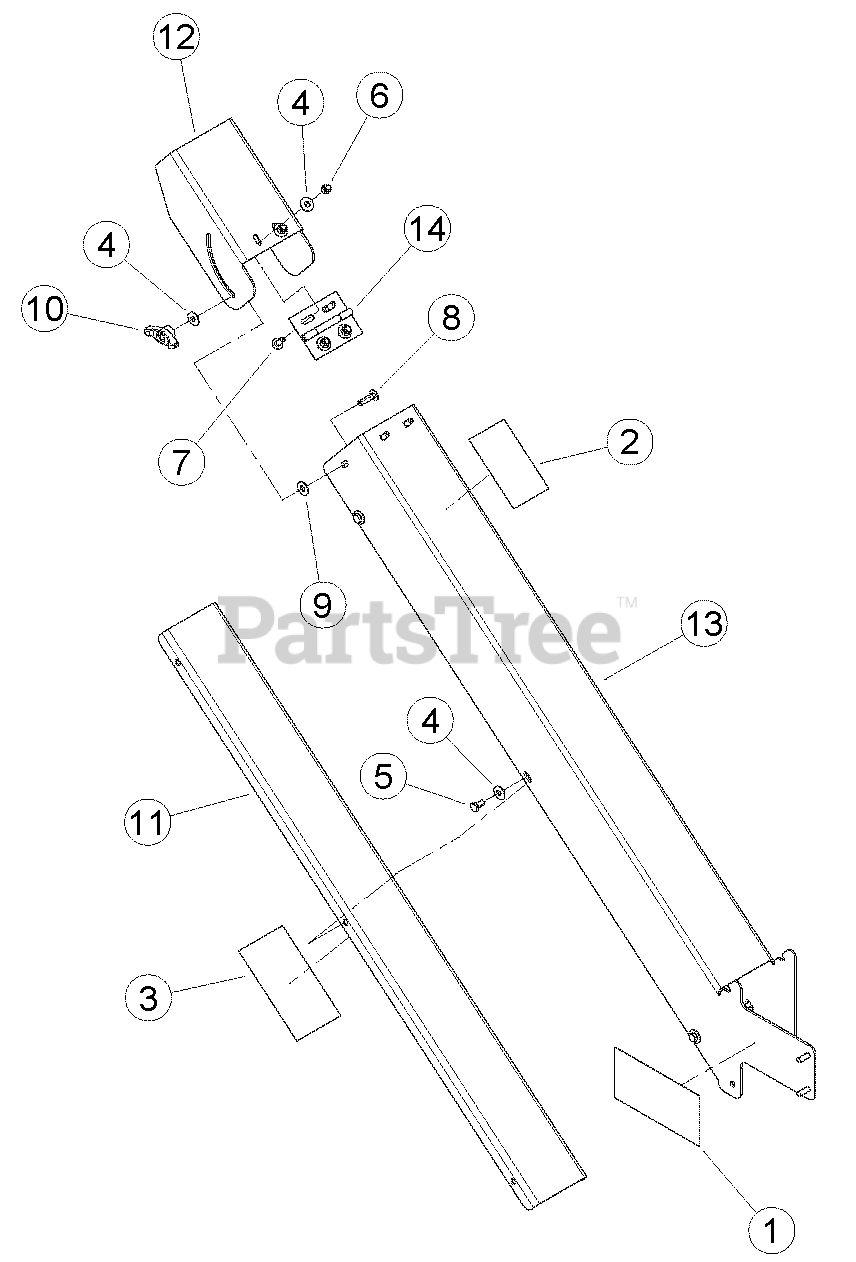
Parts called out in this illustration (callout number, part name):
1	DECAL, KNIFE ACCESS ISO
2	DECAL, DISCHARGE ISO
3	DECAL, BLADE DANGER ISO
4	WASHER, 5/16" FLAT ZP
5	BOLT,5/16 X 5/8 GR5 HEX CPS ZP
6	KNOB, SPOUT 5/16-18
7	NUT, 5/16" NE NYLOCK ZP
8	BOLT, 5/16X3/4 GR5 NC ZP CRG
9	BOLT, 5/16 X 1-1/4" GR5 ZP CRG
10	WASHER, 5/16"ID 7/8"OD NYLON FLAT
11	WELDMENT, TOP DISCHARGE CHUTE
12	CAP, DISCHARGE
13	WELDMENT, CHIPPER DISCHARGE
14	HINGE, DISCHARGE CAP
